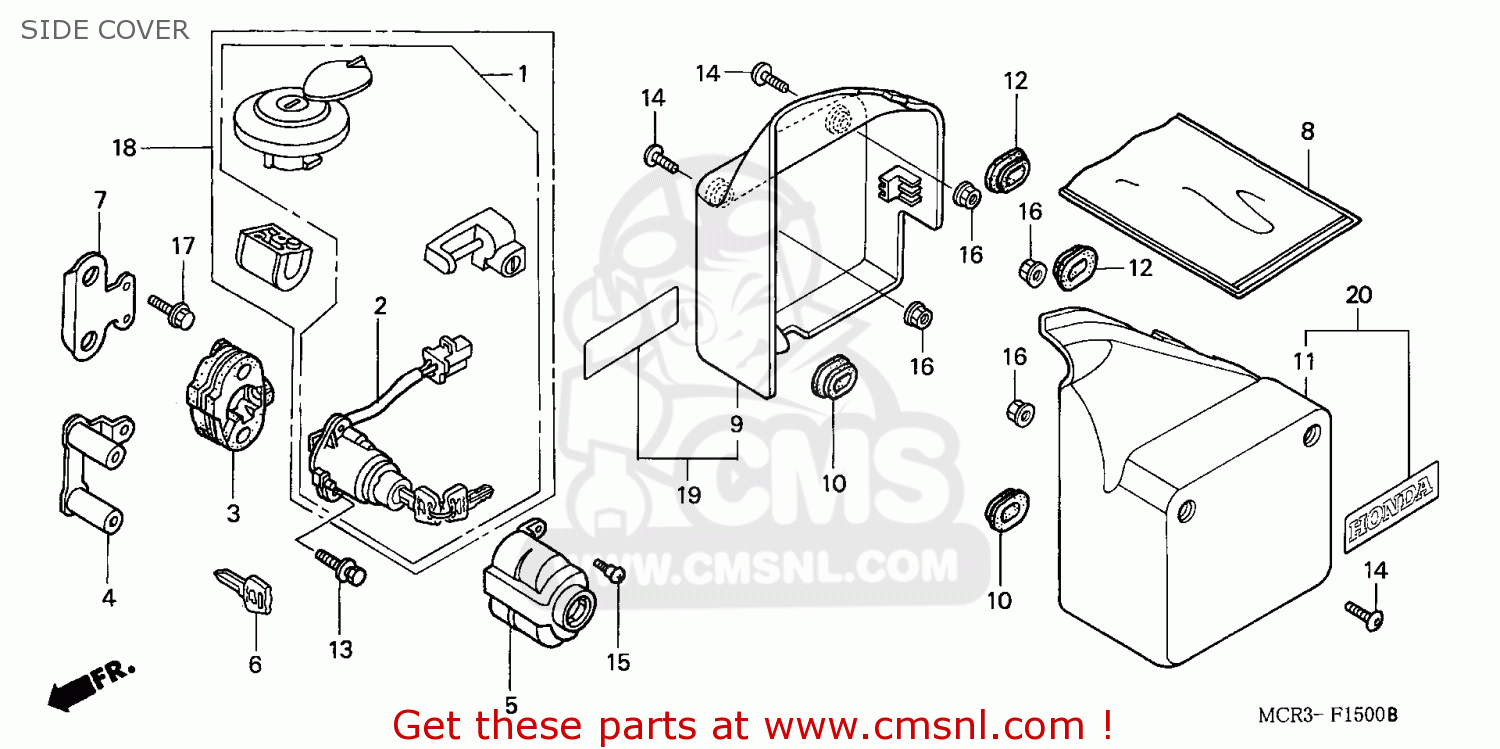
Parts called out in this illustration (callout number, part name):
2	SWITCH ASSY,COMB
3	BASE,COMBI SW
4	COLLAR,COMBI SW
5	COVER,COMBI SW
6	KEY,BLANK NO.1
7	STAY,IGN.SW.
8	BAG,SERVICE BOOK
9	COVER,R SIDE
10	CASE,GROMET
11	COVER,L SIDE
12	GROMMET A SIDE COVER
13	BOLT,BREAK OFF 6M
14	SCREW,PAN,5X14
15	SCREW,RR,COVER
16	NUT,FLANGE,5MM
18	KEY SET
